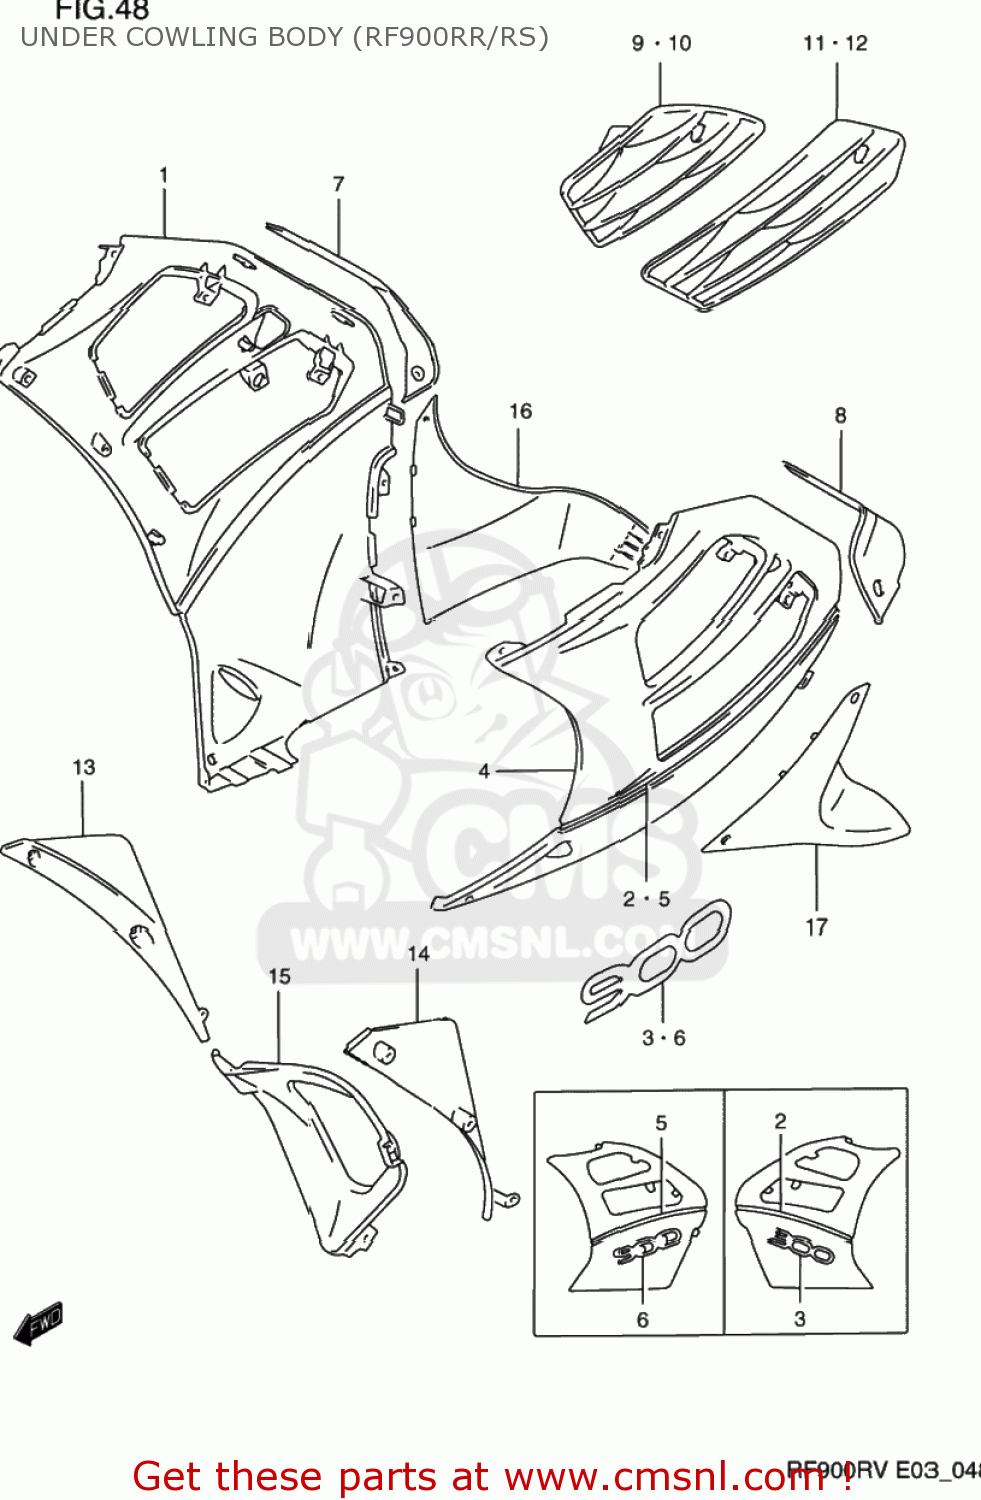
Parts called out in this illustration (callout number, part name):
1	COWLING ASSY,UNDER,R
2	TAPE,UNDER COWL,R
3	EMBLEM,COWLING UNDER
4	COWLING ASSEMBLY,UNDER,LEFT
5	TAPE,UNDER COWLING,LEFT
6	EMBLEM,COWLING UNDER
7	PANEL,UNDER,R
8	PANEL,UNDER,L
9	COVER,UNDER COWL UPR,R
10	COVER,UNDER COWL UPR,L
11	COVER,UNDER COWL LWR,R
12	COVER,UNDER COWL LWR,L
13	COWLING,UNDER INNER,R
14	COWLING,UNDER INNER,L
15	COWLING,UNDER CTR
16	COWLING,UNDER RR,R
17	COWLING,UNDER RR,L
